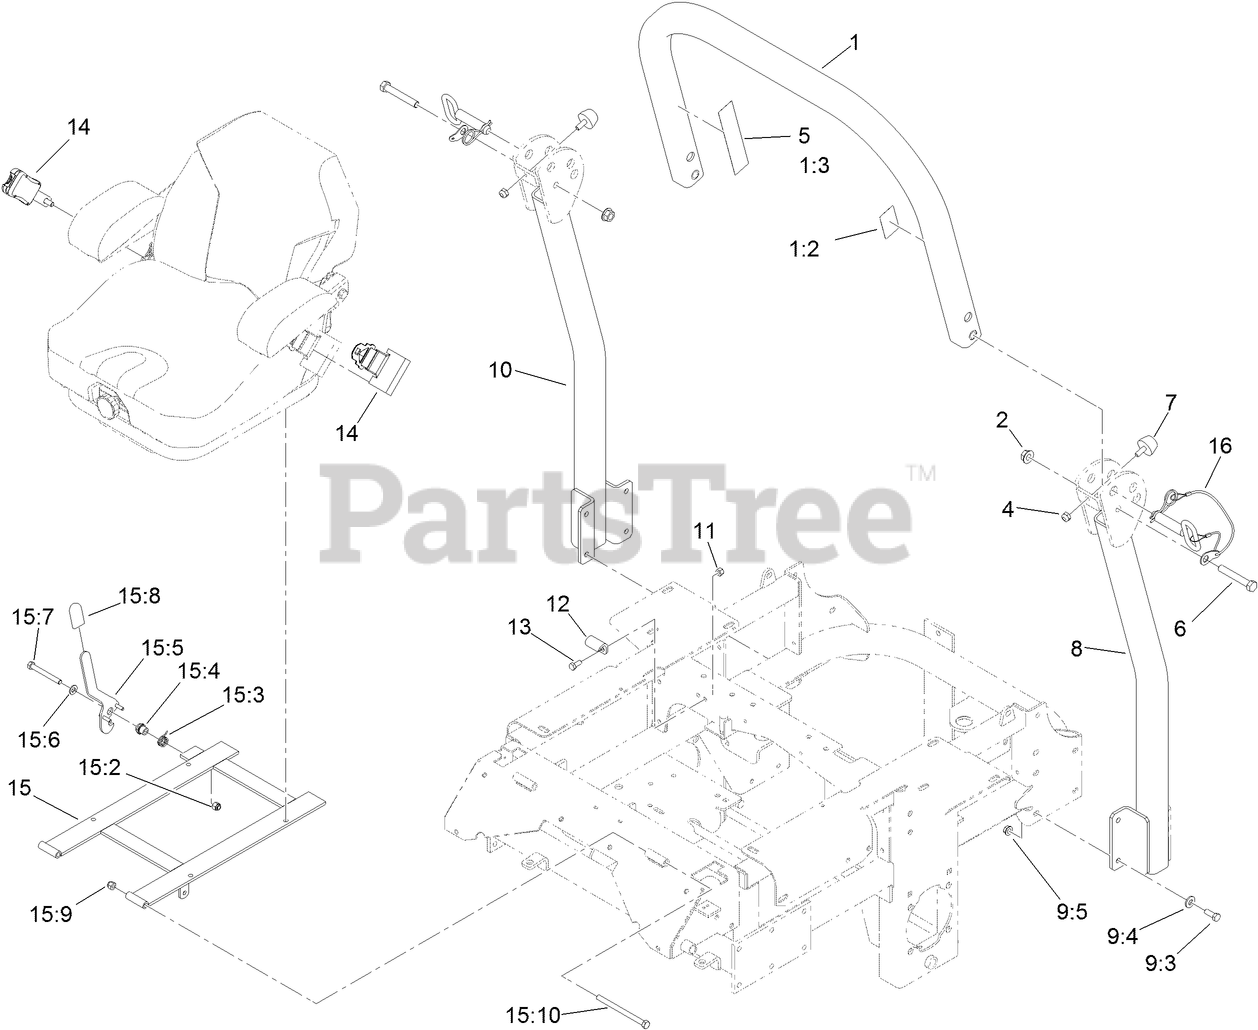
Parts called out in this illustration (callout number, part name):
1	Deck ASM
1:2	DECAL-ROPS
1:3	DECAL-WARNING, FOLDING ROPS
2	NUT-HF
4	NUT-LOCK, NI
5	DECAL-WARNING
6	SCREW-HH
7	BUMPER-RUBBER
8	Deck ASM
9	Deck ASM
9:3	SCREW-HH
9:4	WASHER-BELLEVILLE
9:5	NUT-HHF, WHIZ
10	Deck ASM
11	NUT-LOCK, NI
12	CATCH-LATCH, SEAT
13	SCREW-HH
14	SEAT BELT KIT
15	SEATFRAME ASM
15:2	NUT-LOCK, NI
15:3	SPRING-TORSION
15:4	BUSHING-LATCH, SEAT
15:5	LATCH ASM
15:6	WASHER-FLAT
15:7	SCREW-HH
15:8	GRIP-LEVER
15:9	NUT-LOCK, NI
15:10	SCREW-HH
16	PIN-FOLD, ROPS
